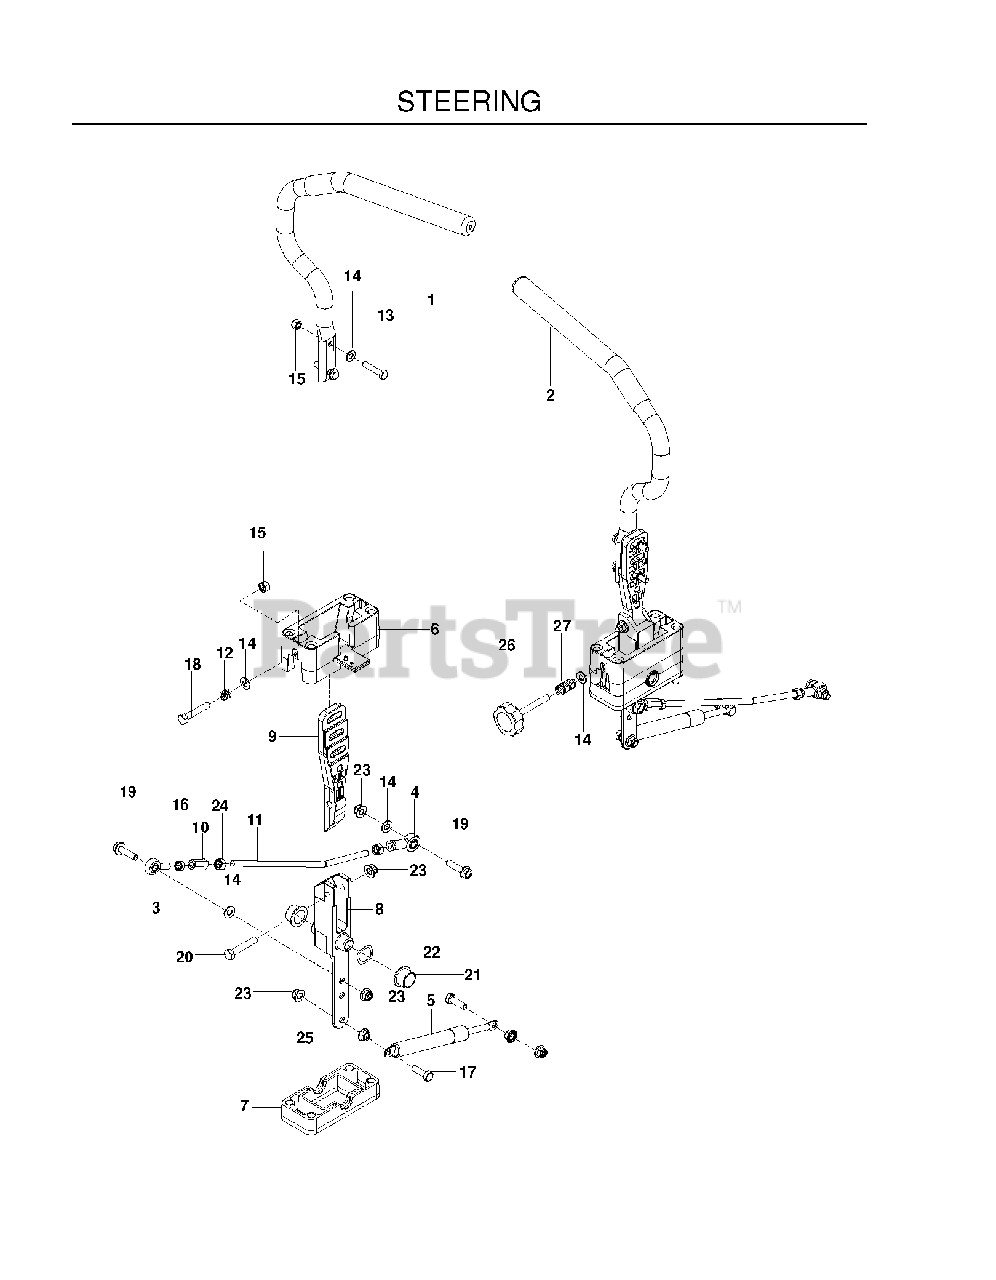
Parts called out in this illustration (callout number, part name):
1	LEVER.DRIVE.W/GRIP.RIGHT
2	LEVER.DRIVE.W/GRIP.LEFT
3	RB ROD.END.LH
4	RH ROD END
6	BLOCK, UPPER
7	BLOCK, LOWER
8	PIVOT.SECTION.DRIVE.CONTROL
9	MOUNT, DR CNTRL HANDLE
10	ROD END COUPLER
11	ROD, CONTROL
13	CAPSCREW 5/16 X 1/1/2 HEX HEAD
14	FLAT WASHER 5/16 SAE
15	NUT 5/16 NYLOC
16	NUT 5/16F LEFTHAND
17	HCS 5/16C X 1
18	HCS 5/16-18X1-3/4 TPBLT
19	HHFS 5/16-18 X 1.25 TPBLT GD 5
20	HCS 5/16C X 1 3/4
21	BEARING, FLANGE
22	WASHER, .825 X 1.087, WAVE
23	5/16-18 NYLOC FLANGE NUT
25	NUT 5/16C WHIZ
